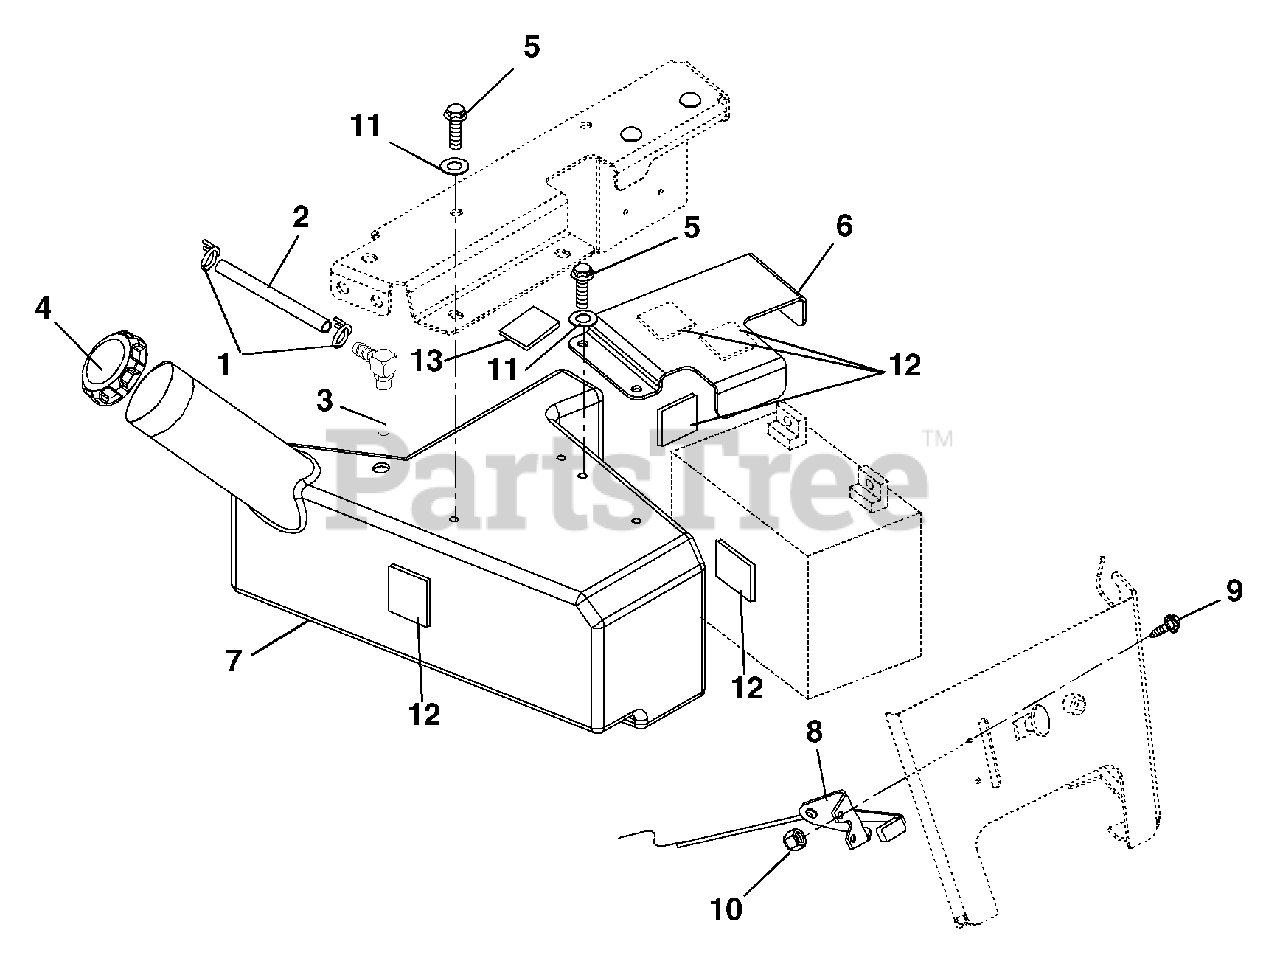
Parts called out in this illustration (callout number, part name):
1	CLAMP-HOSE WIRE .490/.510X.116
2	GAS LINE-BULK 1/4" I.D.
3	TANK FITTING
4	FUEL CAP
5	BLT-SERHFWH .25-20X.75 YWZC
6	BRACKET-BATTERY
7	TANK-FUEL
8	THROTTLE CABLE
9	@SCR-MCH 10-24X.50 HWH YWZC
10	@NUT-LK-NYL 10-24 W/INSRT YWZC
11	@WSHR-LK .31X.078 REG YWZC
12	PAD, FOAM
13	VHB TAPE 4941F
